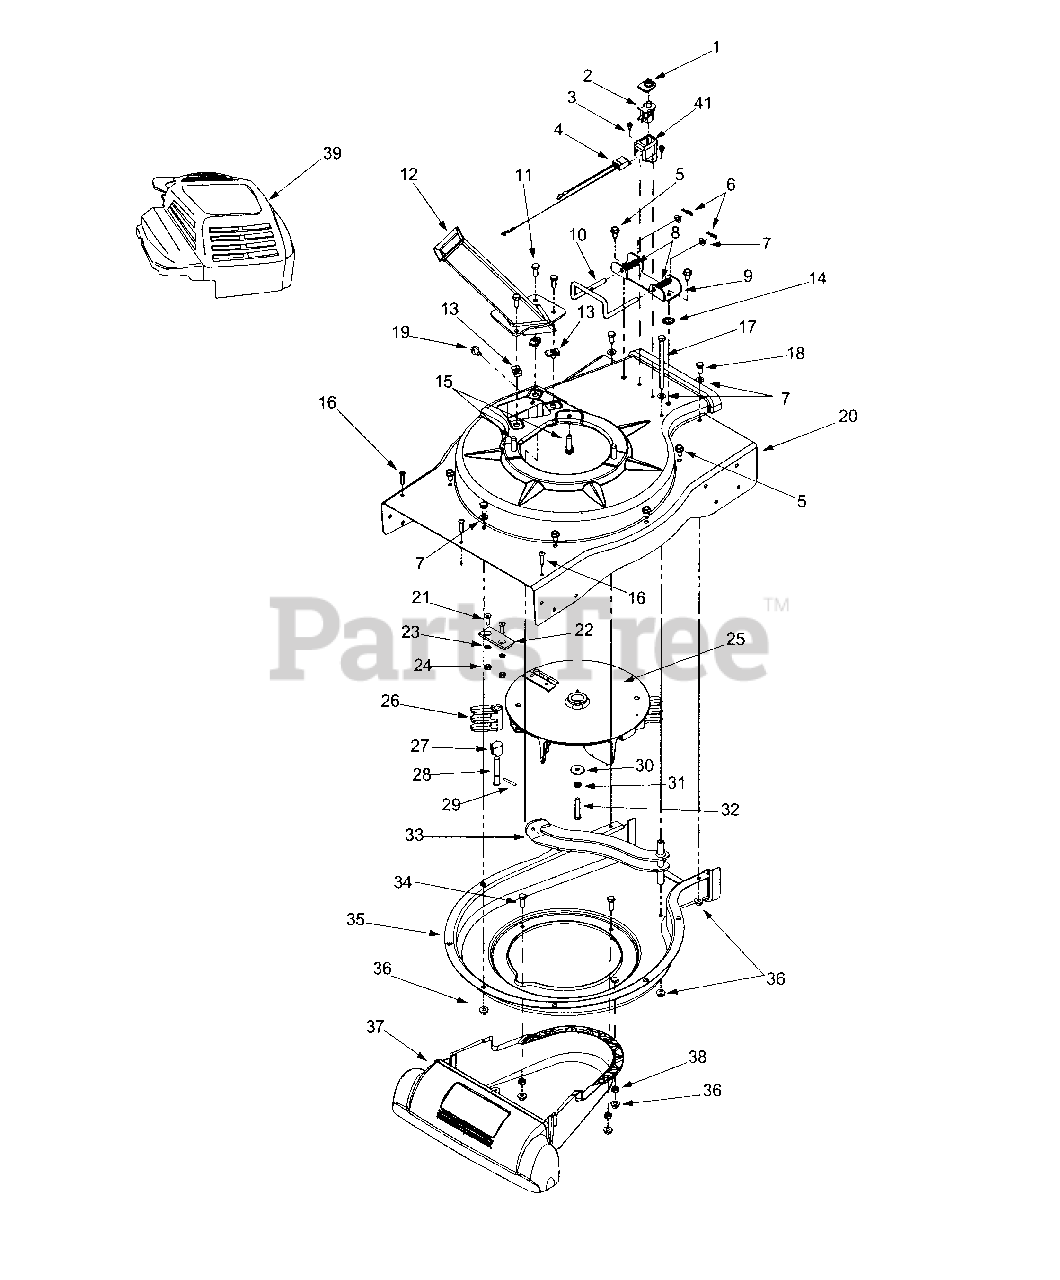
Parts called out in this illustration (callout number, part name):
1	Switch Cover
2	Safety Switch
3	Hex Washer Screw #10-16 x .50
4	Wire Harness
5	Hex Washer Screw 5/16-18 x .625
6	Cotter Pin
7	Flat Washer .330 ID x .630 OD
8	Compression Spring
9	Mounting Bracket
10	Lock Rod
11	Hex Cap Screw 5/16-18 x .75
13	U-Clip Lock Nut 5/16-18
14	External Lock Washer 5/16
15	Hex Washer Screw 3/8-16 x 1.25
16	Screw #12-16 x 1.0
17	Hex Cap Screw 5/16-18 x 4.5
18	Hex Cap Screw 5/16-18 x .625
19	Hex Washer Screw 5/16-18 x .625
22	Chipper Blade
23	Lock Washer 5/16
24	Hex Lock Nut 5/16-24
25	Impeller Assembly
26	Flail Blade
27	Pin Clip
28	Clevis Pin
29	Spiral Pin
30	Flat Washer .375 ID x 1.25 OD
31	Lock Washer 3/8
32	Hex Cap Screw 3/8-24 x 2.0
33	Screen Assembly
34	Hex Cap Screw 5/16-18 x .875
36	Lock Nut 5/16-18
37	Nozzle Cover
38	Lock Nut 5/16-18
40	Screw #8-18 x 1.25
41	Safety Switch Cover
